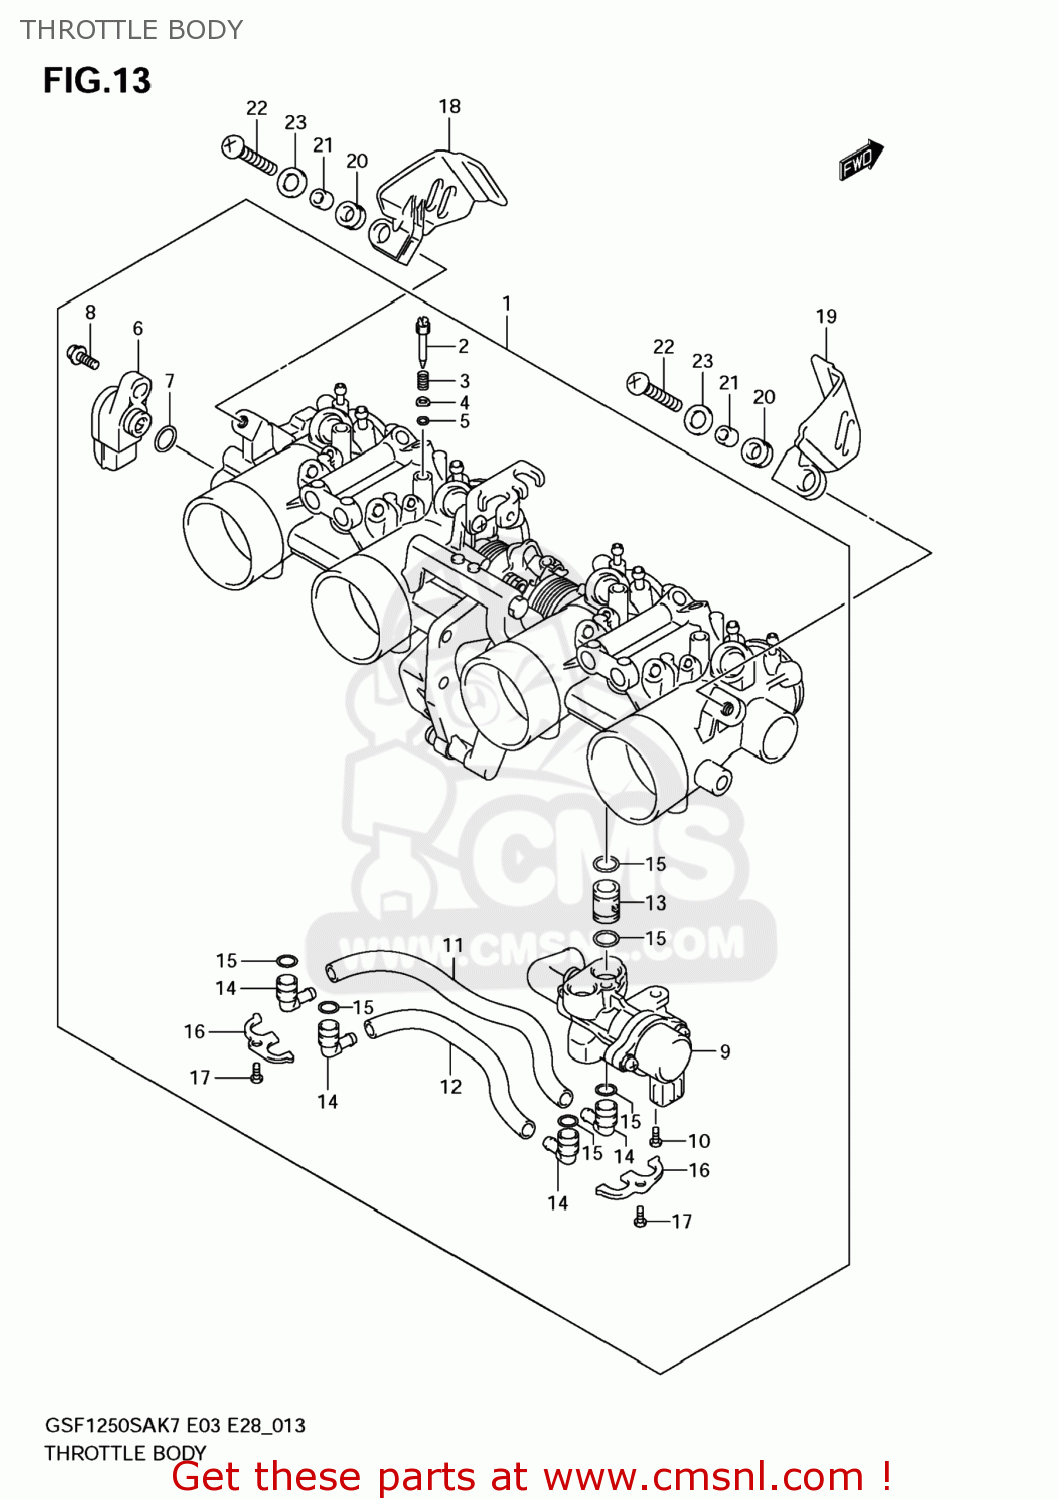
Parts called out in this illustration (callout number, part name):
1	BODY ASSY,THROTTLE
2	SCREW
3	SPRING,THROTTLE SCREW
4	WASHER
5	O RING,PILOT AIR SCREW
6	SENSOR
7	O RING
8	SCREW
9	ACTUATOR
10	SCREW
11	HOSE
12	HOSE
13	PIPE
14	NIPPLE
15	O RING
16	PLATE
17	SCREW
18	COVER,FUEL INJECTOR
19	COVER,FUEL INJECTOR
20	HOLDER
21	RING
22	SCREW
23	WASHER
